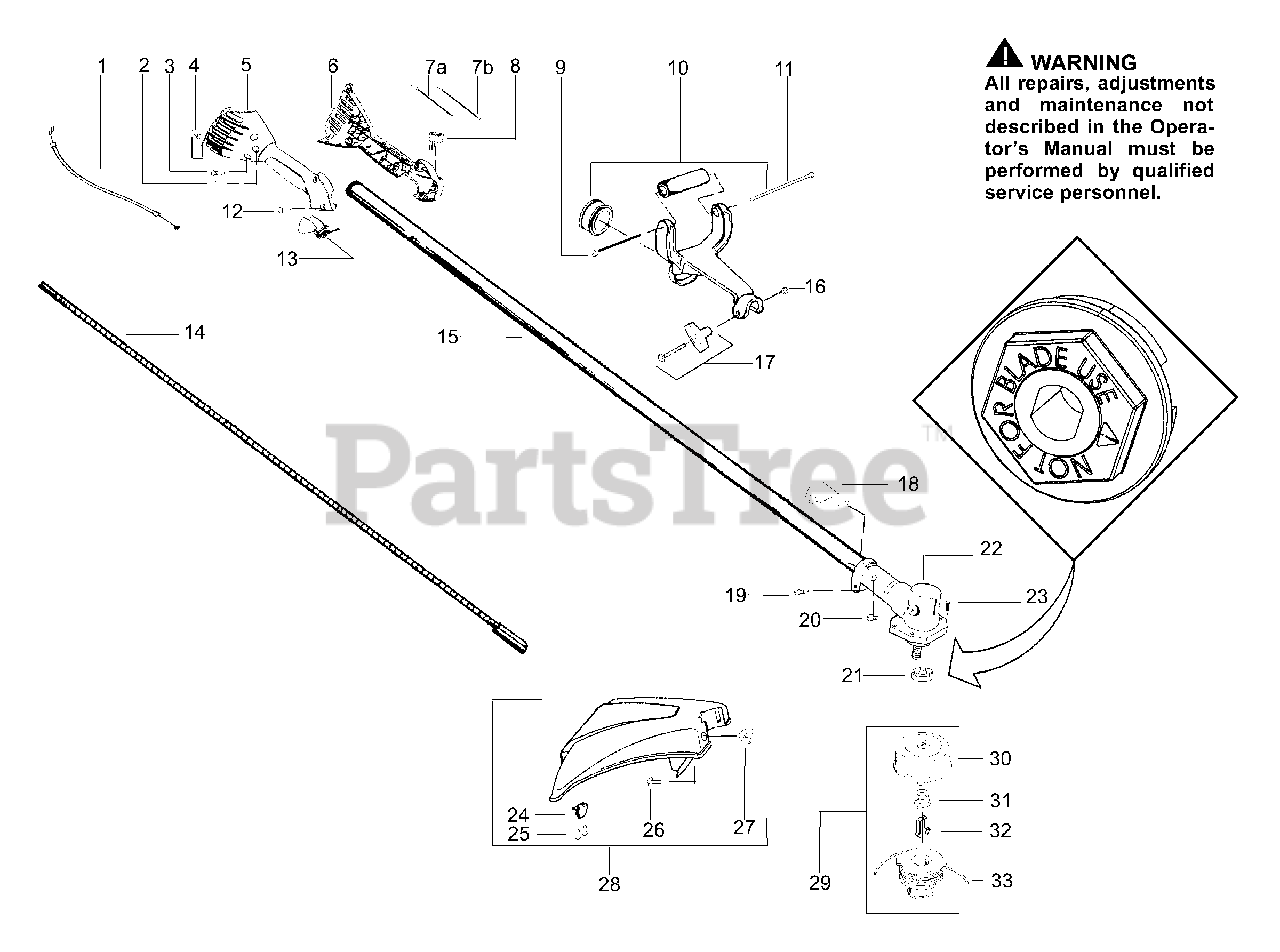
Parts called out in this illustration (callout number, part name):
1	Assy-Throttle cable
2	Screw-alignment
3	Screw-10-24
4	Screw-handle/fan hsg.
5	Throttle Hsg.-Right
6	Kit-Left Throttle Hsg.
7A	Assy-Wire Assy-Front wire
7B	Assy-Wire Assy- Front Wire (upper)
8	Kit-Switch
9	Nut 12-24
10	Assy-Antivibe Handle
13	Trigger-Throttle
14	Shaft-Flex
15	Assy-Driveshaft
16	Nut 1/4-20"
17	Assy-"T" Handle
18	Bracket - Shield
21	Non-Blade Dust cup
22	Assy.-Gearbox non blade
24	Limiter-Line
25	Screw
27	Wingnut
28	Kit-Shield Ass'y.
29	Accy.- Cutting Head
30	Assy. - Hub/Arbor (3/8lh , 2x)
31	Spring - Return
32	Retainer - Spool
33	Accy.-Wound Spool
